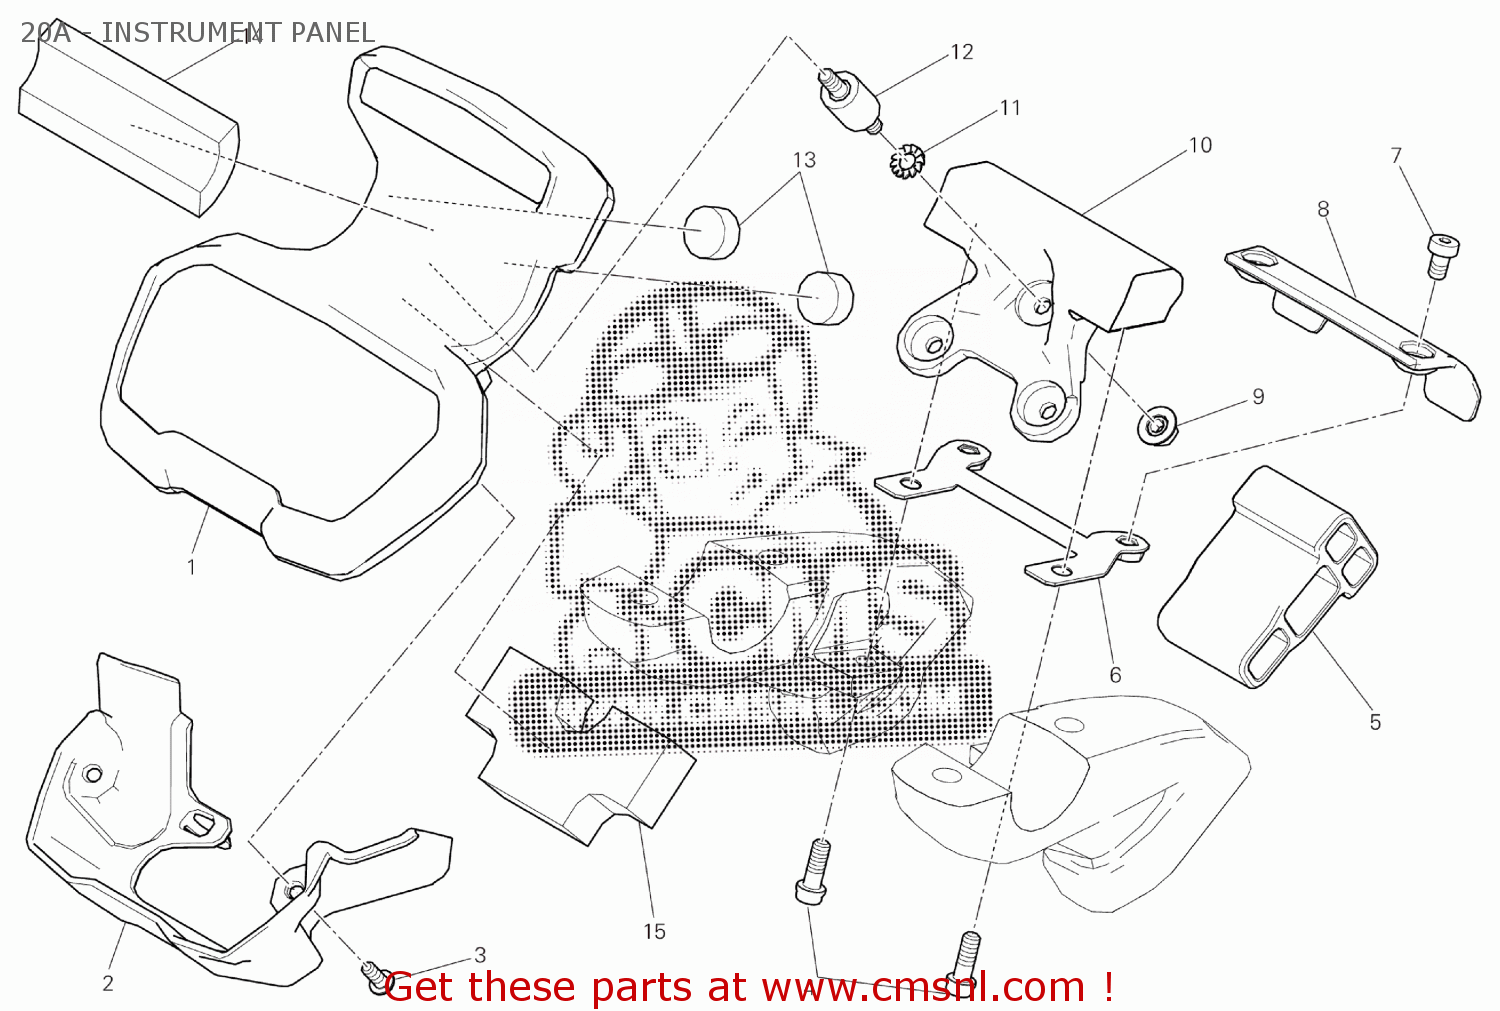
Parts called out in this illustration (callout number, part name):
1	INSTRUMENT PANEL
2	COVER, METER
3	SCREW
4	SCREW TCEIF M5X14
5	BRACKET, CONNECTOR
6	BRACKET
7	SCREW
8	COVER
9	NUT M5
10	HOLDER
11	WASHER, SPRING
12	VIBRATION DAMPER
13	VIBRATION DAMPER
14	VIBRATION DAMPER
15	VIBRATION DAMPER
